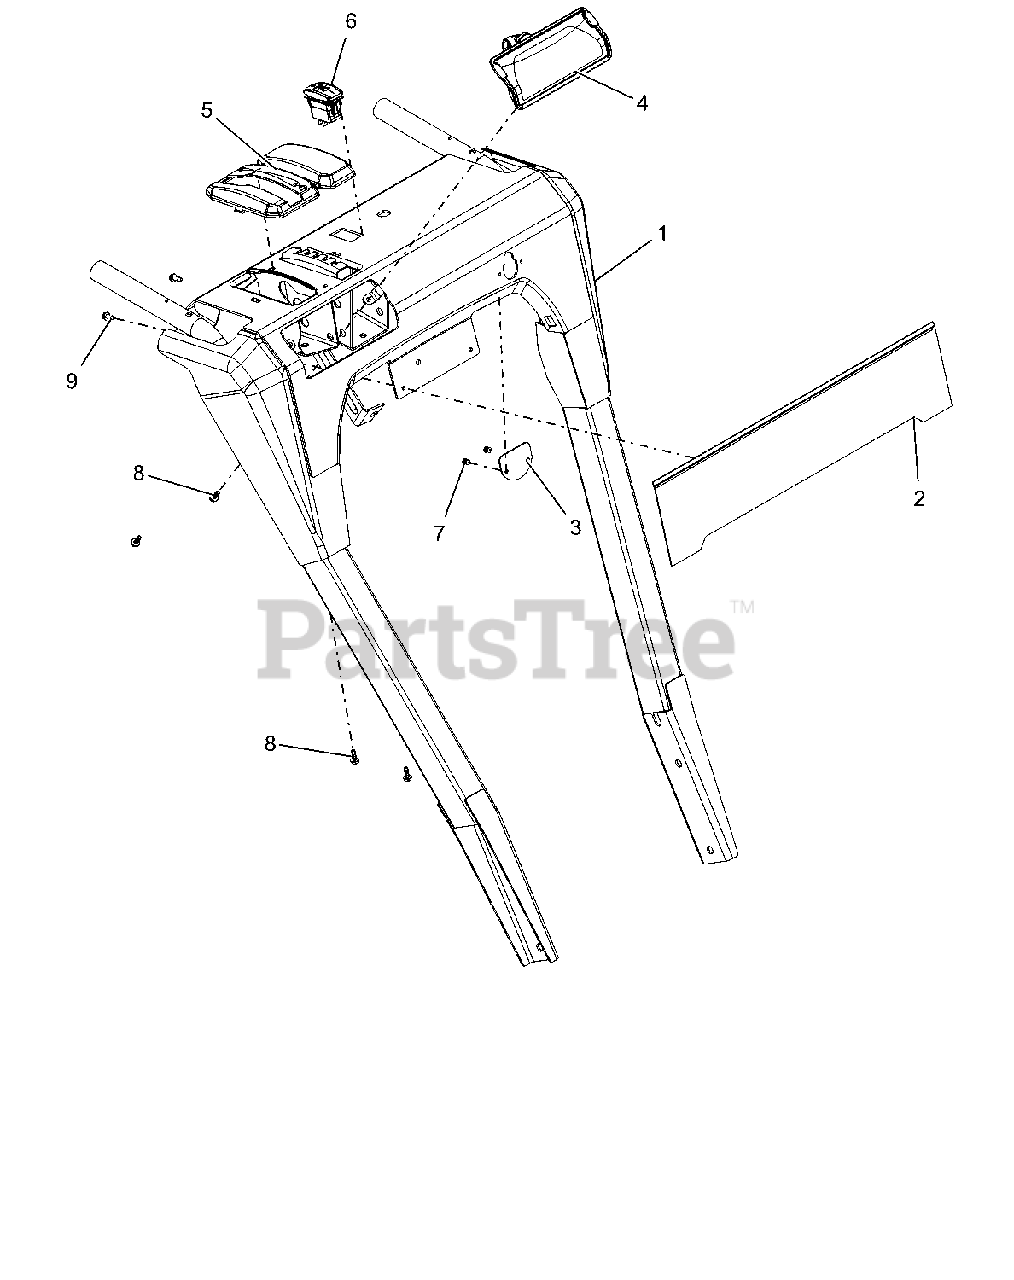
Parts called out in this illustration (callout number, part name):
1	PANEL, DASH - W/CTR DECAL(12V)
2	WLDMT, BRAND PLATE
3	COVER, DASH BRKT, BRUSH
4	HEADLIGHT ASY, HOLO 15W 2 SHOT
5	BEZEL, SHIFT - HYDRO BRUSH
6	SWITCH,ROCKER SPST-ON/OFF
7	RVT-POP #43 .125X.313 STL ZINC
8	SCR-TAP #10X.50 BOSS INDHXHD
9	SCR-TAP 10-24X.50 HWH TR YWZC
